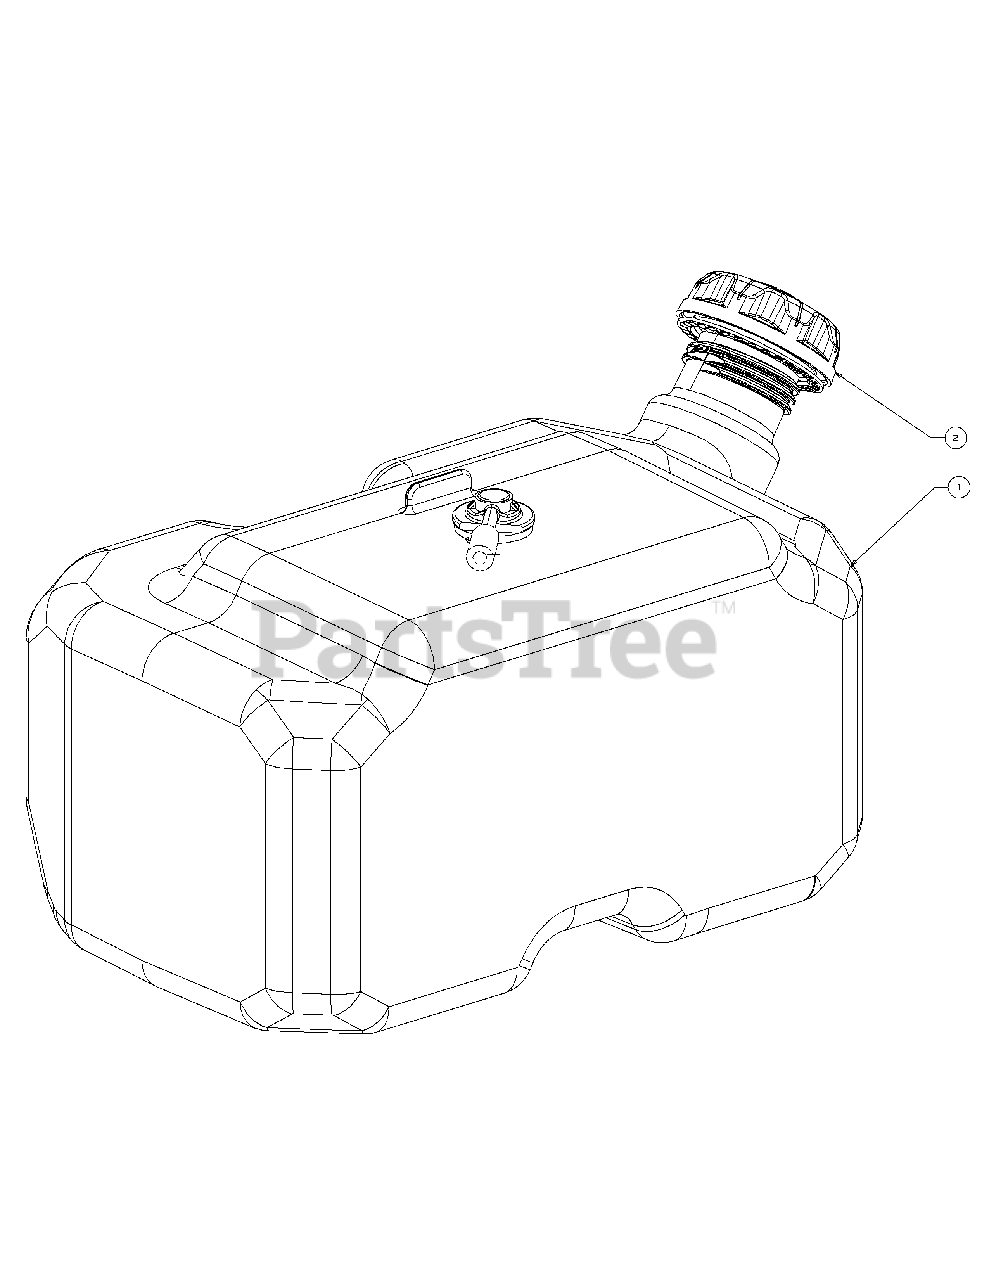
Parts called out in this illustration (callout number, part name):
1	Tank Asm-Fuel 3 Gal
1	Grommet-Rubber 23.0
1	Valve-Rollover Fuel
2	Cap:Fuel:2.25"
